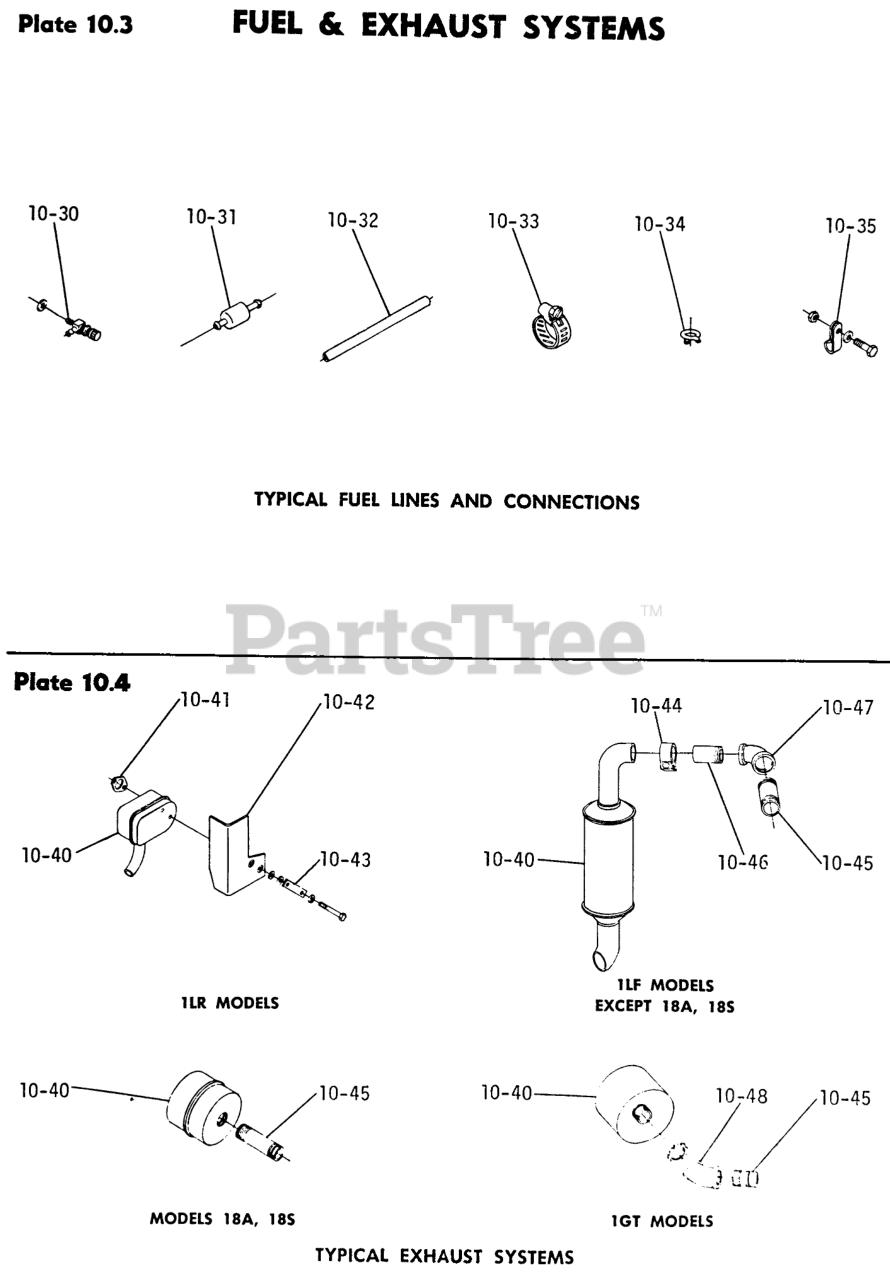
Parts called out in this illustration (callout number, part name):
10-30	S/A FUEL VALVE
10-35	Bolt 5/16-18 x 1
10-35	Nut-Nylok
10-35	Bolt Hex 5/16-18
10-35	Nut 5/16-18
10-35	Washer
10-35	Bolt, 1/4-20 x 3/8
10-40	Muffler
10-42	Shield-Heat
10-43	Bar-Support
10-43	Bolt Hex 5/16-18
10-43	Bolt, 5/16-18 x 3
10-43	Nut, 5/16-18
10-43	Lockwasher
10-45	Nipple 3/4 Pipe x 3 1/2
10-45	Nipple 1" x 1 1/2
10-47	Elbow 90 X 1
10-48	Elbow 1" x 45?
